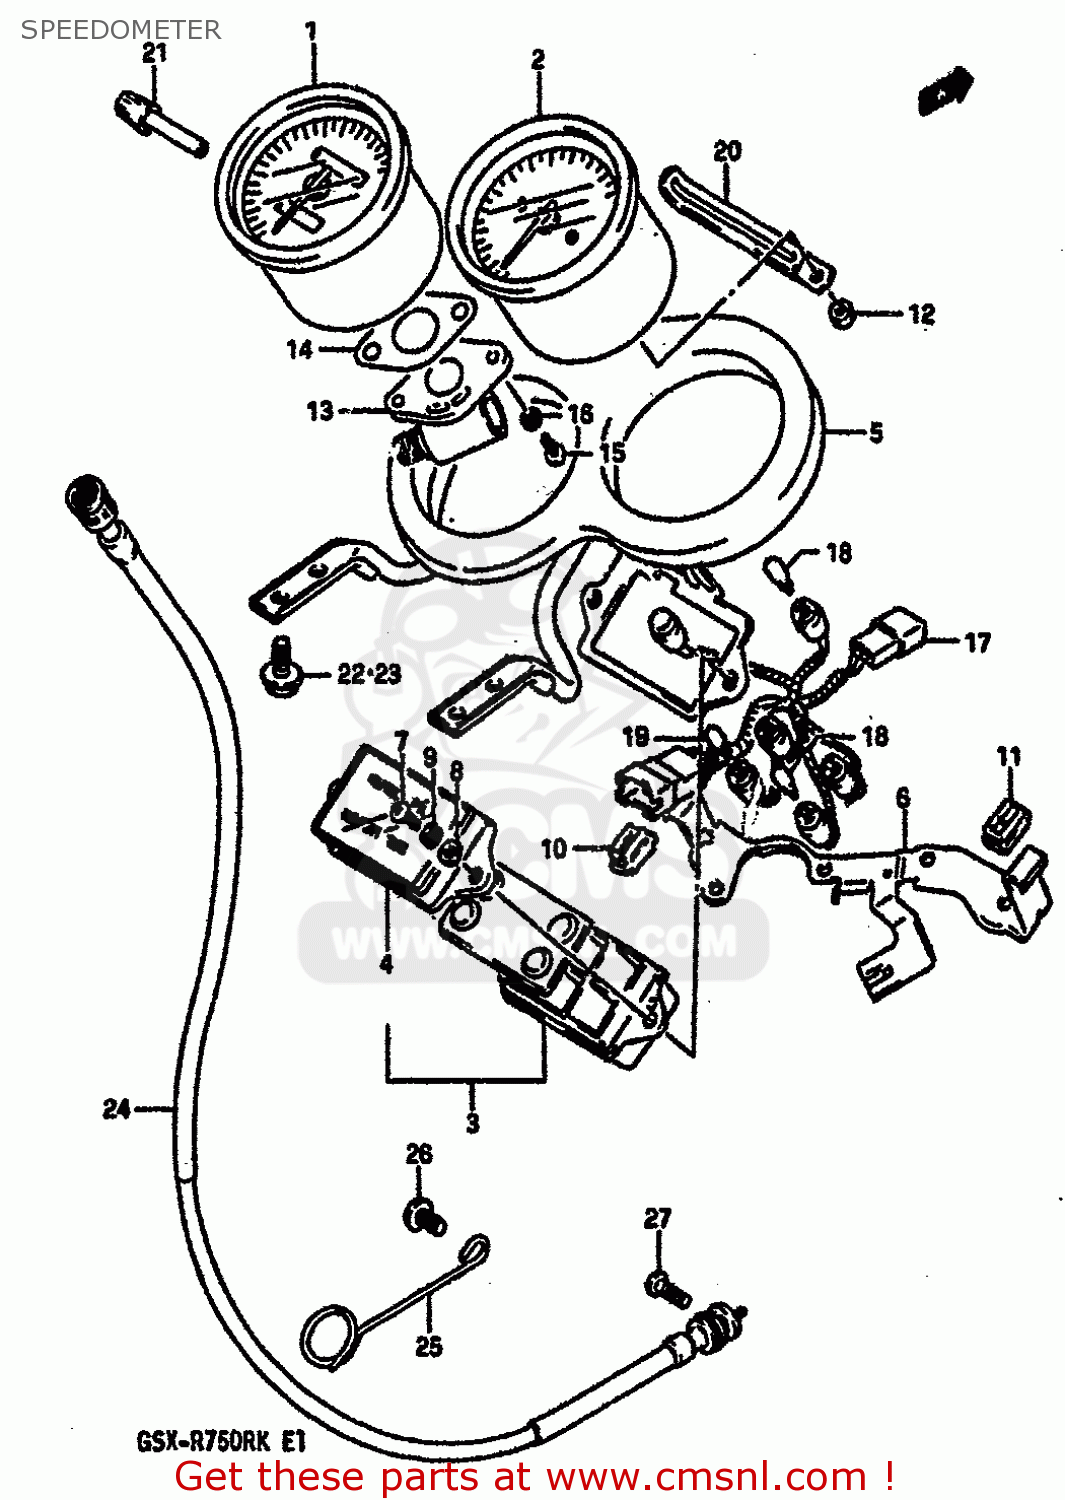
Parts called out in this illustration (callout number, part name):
1	SPEEDOMETER
2	TACHOMETER
3	BOX ASSEMBLY,PILOT LAMP
4	LENS,BOX
5	PLATE,SETTING
6	BRACKET
7	SCREW
8	WASHER
9	WASHER,LOCK 4M
10	DAMPER,LEFT
11	CUSHION
12	NUT
13	GEAR BOX
14	GASKET,METER GEAR BOX (NAS)
15	SCREW
16	WASHER,LOCK 4M
17	SOCKET,METER
18	BULB(12V3W,T6.5)
19	BULB(12V1.7W,T6.5)
20	CLAMP
21	KNOB,TRIP
22	BOLT 6X12
23	BOLT
24	CABLE ASSEMBLY,SPEEDOMETER
25	GUIDE,SPEEDOMETER CABLE,R
26	SCREW
27	SCREW
